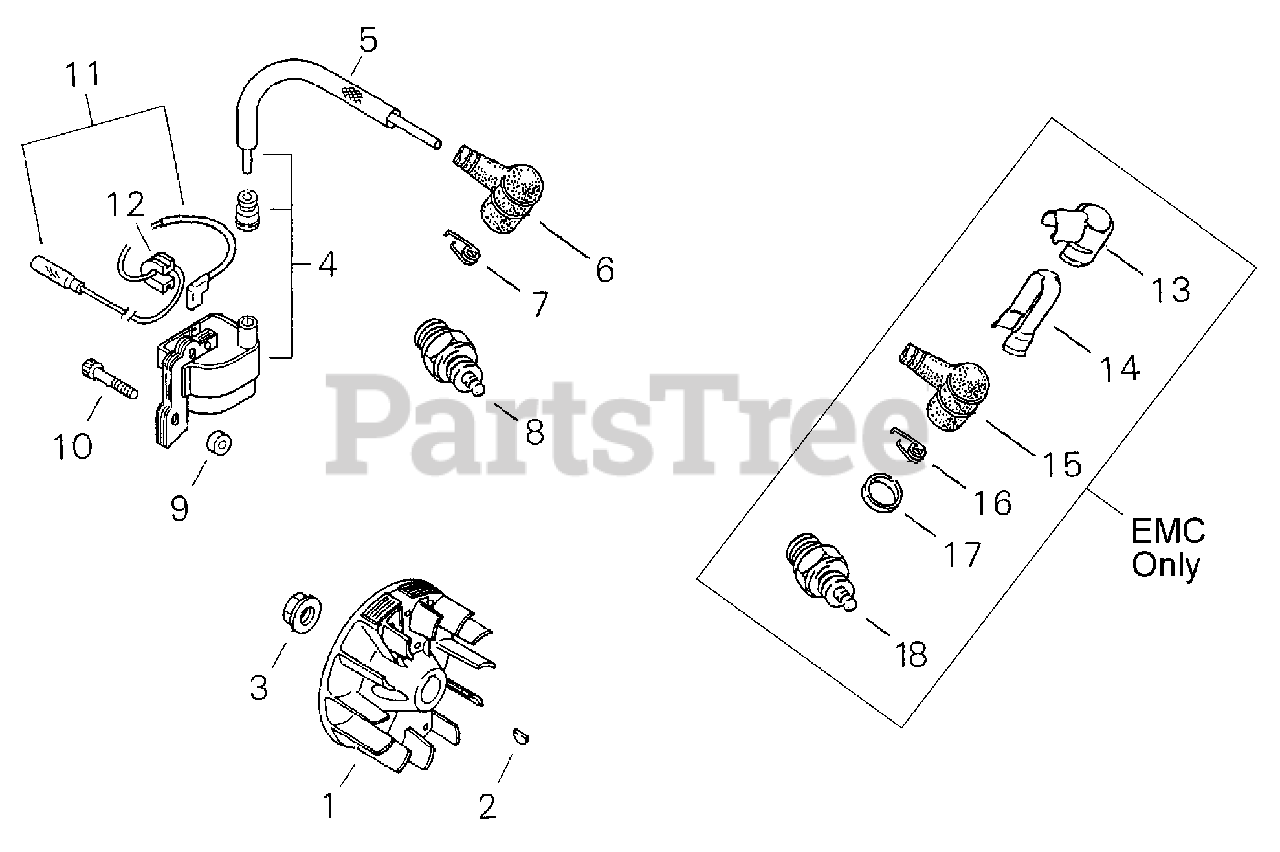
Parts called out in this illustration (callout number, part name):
2	KEY - 3X10
3	NUT - 8
4	IGNITION COIL ASSY
5	INSULATOR SLEEVE
5-1	FLYWHEEL
6	SPARK PLUG CAP
7	TERMINAL, SPARK PLUG CAP
8	SPARK PLUG -- CJ8
9	INSULATOR
10	SCREW - 4X26
11	LEAD ASSY
12	GROMMET
13	CAP, SPARK PLUG
14	SHIELD
15	CAP, SPARK PLUG
16	TERMINAL, SPARK PLUG CAP
17	SEAL, DUST
18	SPARK PLUG -- BMR-6A
